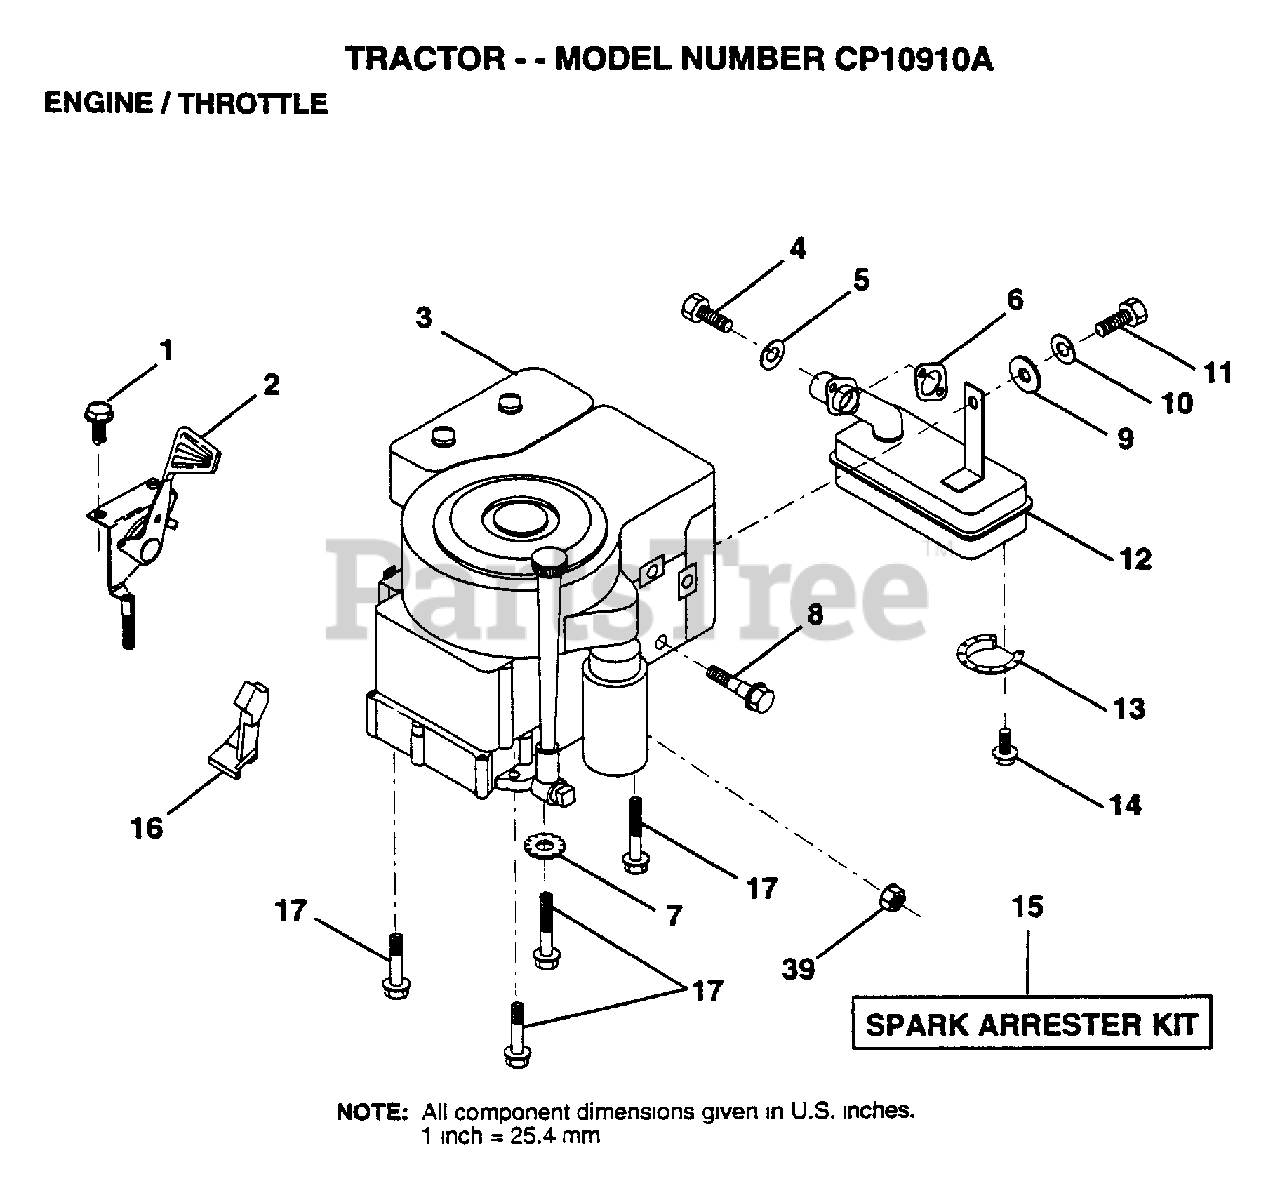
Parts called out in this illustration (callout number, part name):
1	SCREW.1/4-20X1/2
4	SCREW
5	LOCKWASHER
7	LOCKWASHER
8	BOLT T
10	LOCKWASHER
11	BOLT LT
12	MUFFLER
13	DEFLECTOR.222573
16	"STOP,DASH THROTT"
17	SCREW LT
39	NUT
